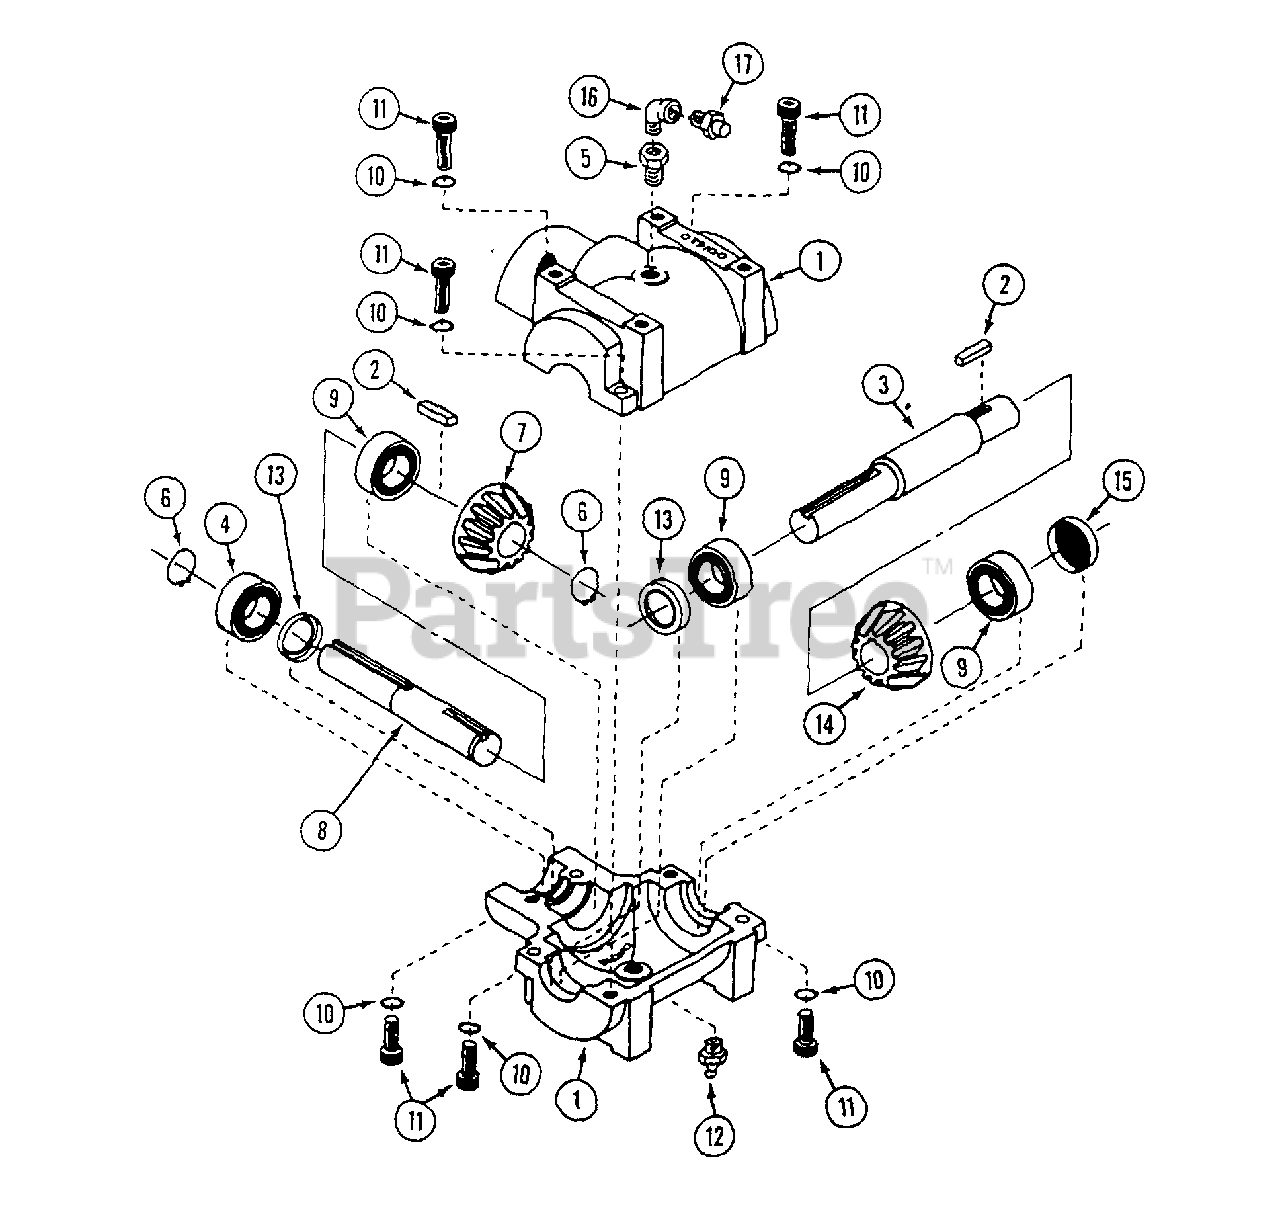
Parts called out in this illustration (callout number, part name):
1	HOUSING - half
2	KEY - 3/16" x 3/16" x 1"
3	SHAFT - input
4	BEARING - ball
5	BUSHING - pipe 1/4" x 1/8
6	RING - retaining
7	GEAR - output shaft
8	SHAFT - output
9	BEARING - ball
10	LOCKWASHER
11	CAP SCREW - allen head
12	FITTING - grease 1/4" NPT
14	GEAR - input shaft
15	PLUG - expansion
16	ELBOW - street 1/8" x 90°.
17	VALVE - relief
